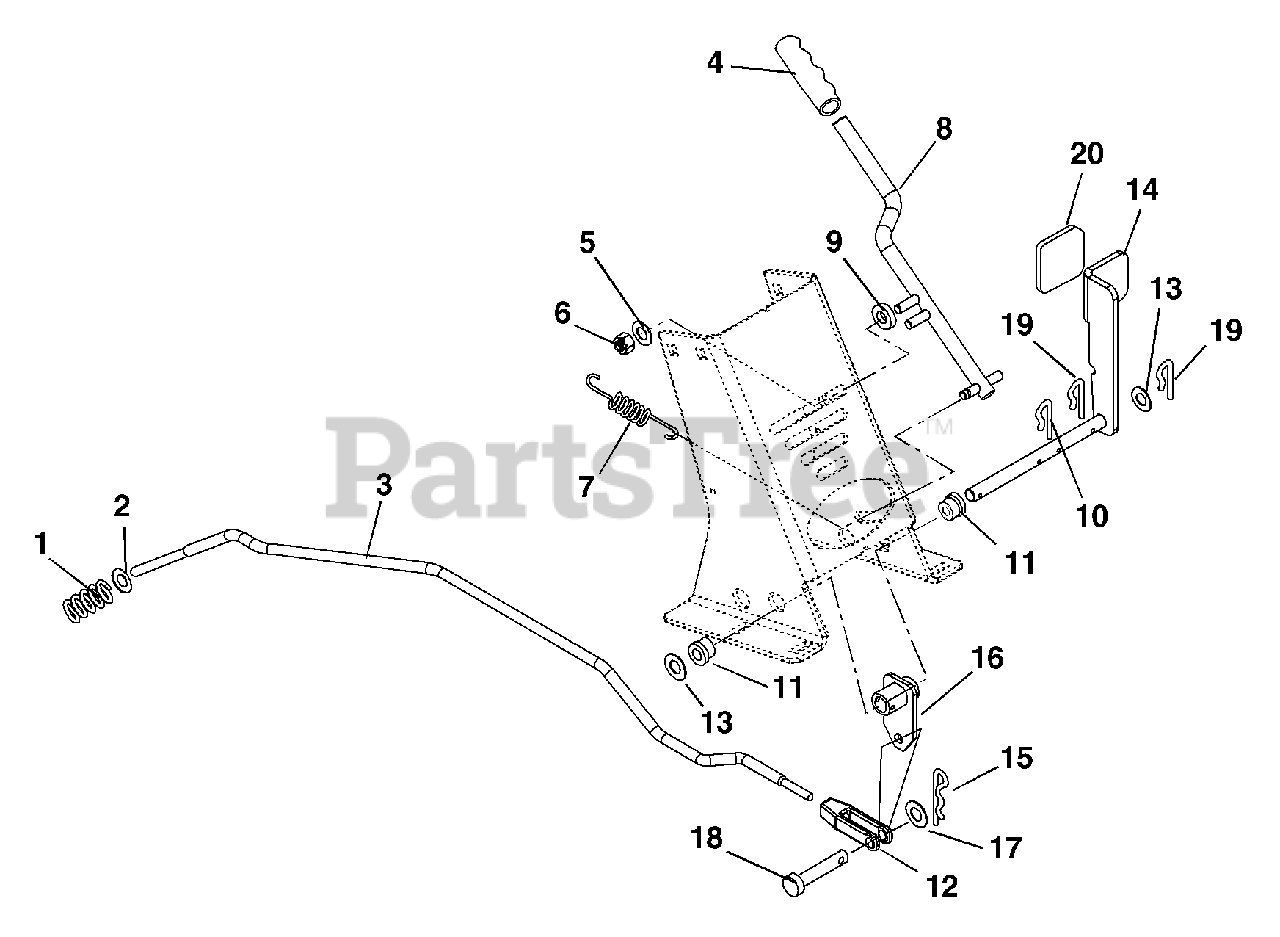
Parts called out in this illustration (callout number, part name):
1	SG-COMP .080X.52X2.90
2	WSHR-FL-STL .328X.87X.179 YWZC
3	ROD, RER BRAKE
5	@WSHR-FL-STL.38X.875X.083 YWZC
6	NUT-LK-TOP-FLG .38-16 BLKZC
7	SG-TENS .048X.44X2.25 WLD 9
8	HANDLE, PARK BRAKE (WLDMNT)
9	BSHG-FLG .406X.88X.270X.140
10	PIN, SPRING CLIP
11	BSHG-FLG .515X.750X.745X1.00NY
12	YOKE, .312-24 X 2.25
13	WSHR-FL-STL .505X1.00X.062YWZC
14	WLDMT-BRAKE PEDAL
15	PIN-HAIR, ENDRIES #25 YWZC
16	BRAKE ROD ARM & HUB
17	WSHR-FL-STL .328X.87X.179 YWZC
18	PIN-CLEV .312X.822 HDND PL
19	CLIP, SPRING
20	GRIP, PEDAL
